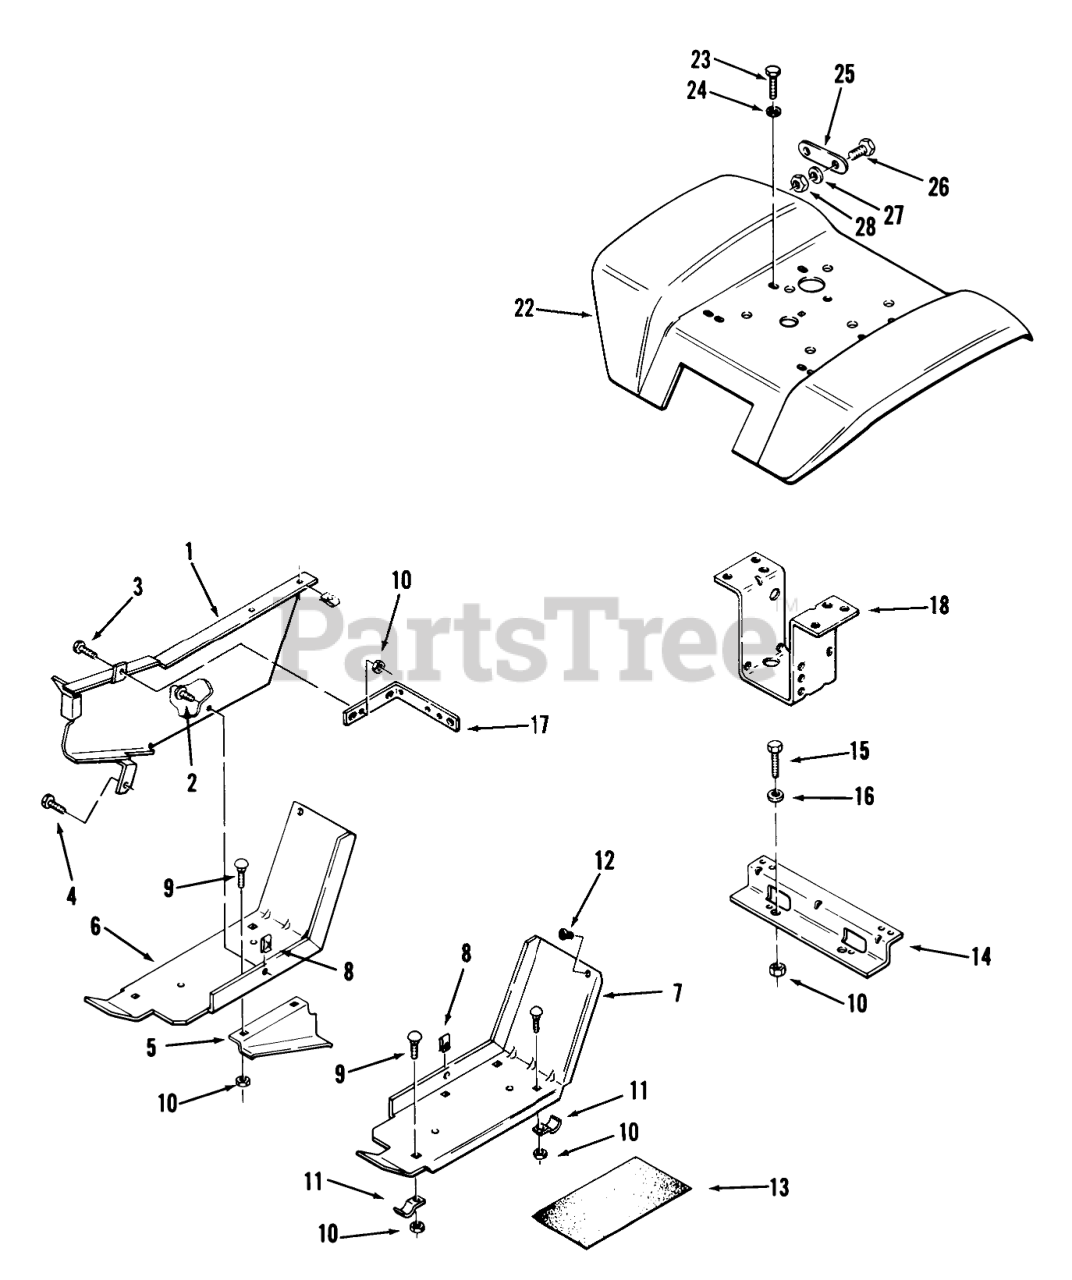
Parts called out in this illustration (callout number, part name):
1	Belt Guard
2	Screw
3	Bolt
4	SCREW
5	GUID-LOWER BLTR
6	Footrest-RH
7	FOOTREST LH R
9	CARRIAGE BOLT -4
10	Nut
11	BRACKET
12	BUMPER-RUBBER
13	PAD-FOOTREST
14	BRACKET-FENDER B
15	Bolt
16	WASHER 5/16 SAE
17	SUPPORT-BELT GUAR B
18	Bracket-Fender Support
19	Fuel Tank Support LH
20	Support-FueITank RH
21	Bolt
22	Fender
23	Bolt
24	WASHER 5/16 SAE
25	REFLECTOR-STICK ON
26	Screw
27	Lockwasher
28	Nut
